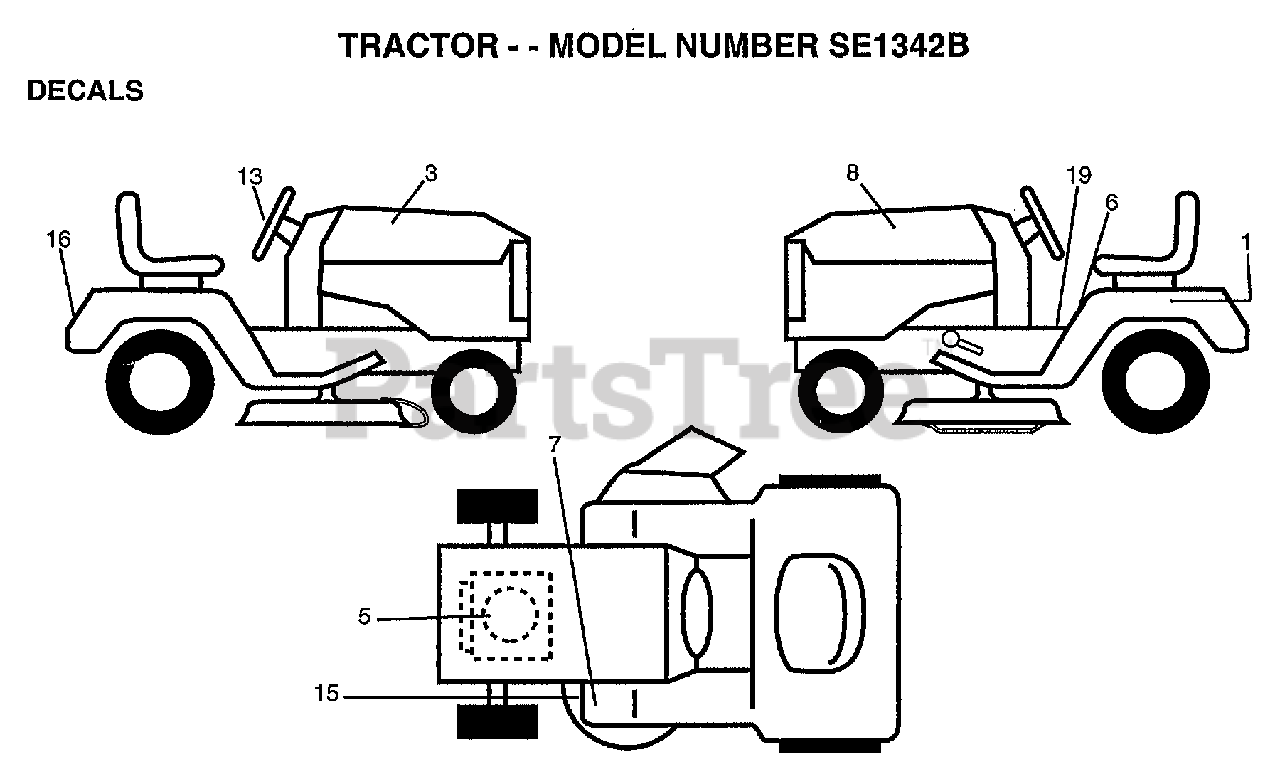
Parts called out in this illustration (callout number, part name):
1	DECAL.BATRY.3-3908
3	DECAL HOOD RH
5	DECAL ENGINE
6	"DECAL DANGER,FEND"
8	"DECAL.HOOD,LH"
13	"DECAL.INS,STRG WH"
15	DECAL
16	DECAL FENDER LOGO
19	"DECAL DASH,OPER."
